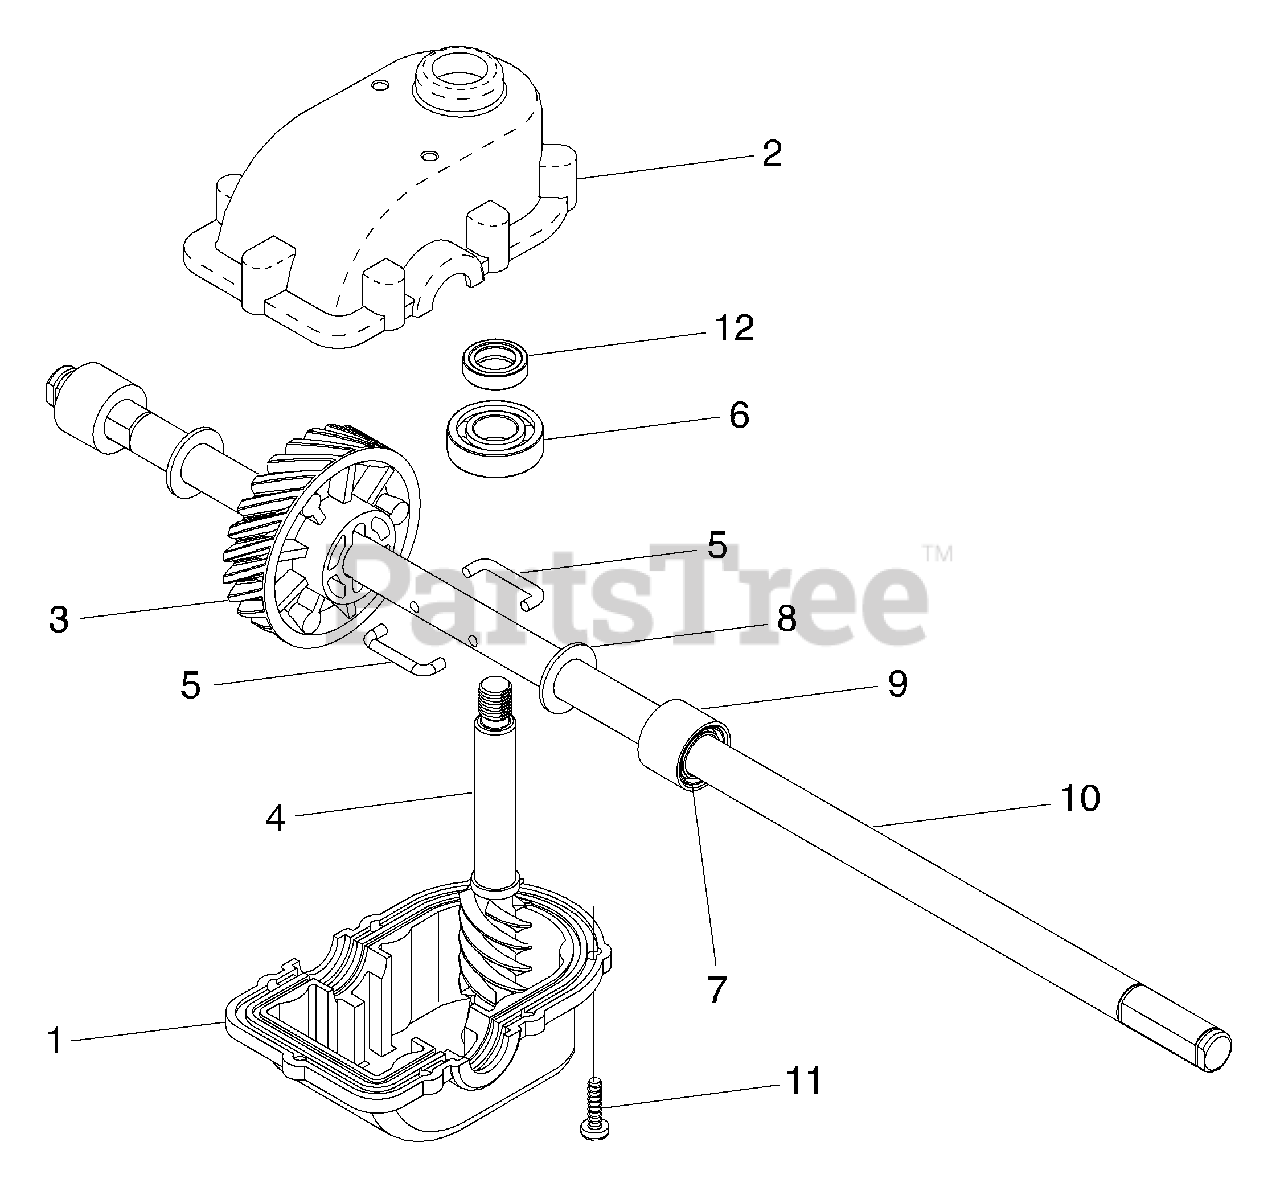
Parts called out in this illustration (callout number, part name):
1	Case, Lower
2	Case, Upper
3	Gear, 24 Teeth
4	Shaft, Worm
5	Wireform
6	Bearing, Ball
7	Seal, Output Shaft
8	Washer
9	Bushing
10	Shaft, Output
12	Seal, Worm Shaft
